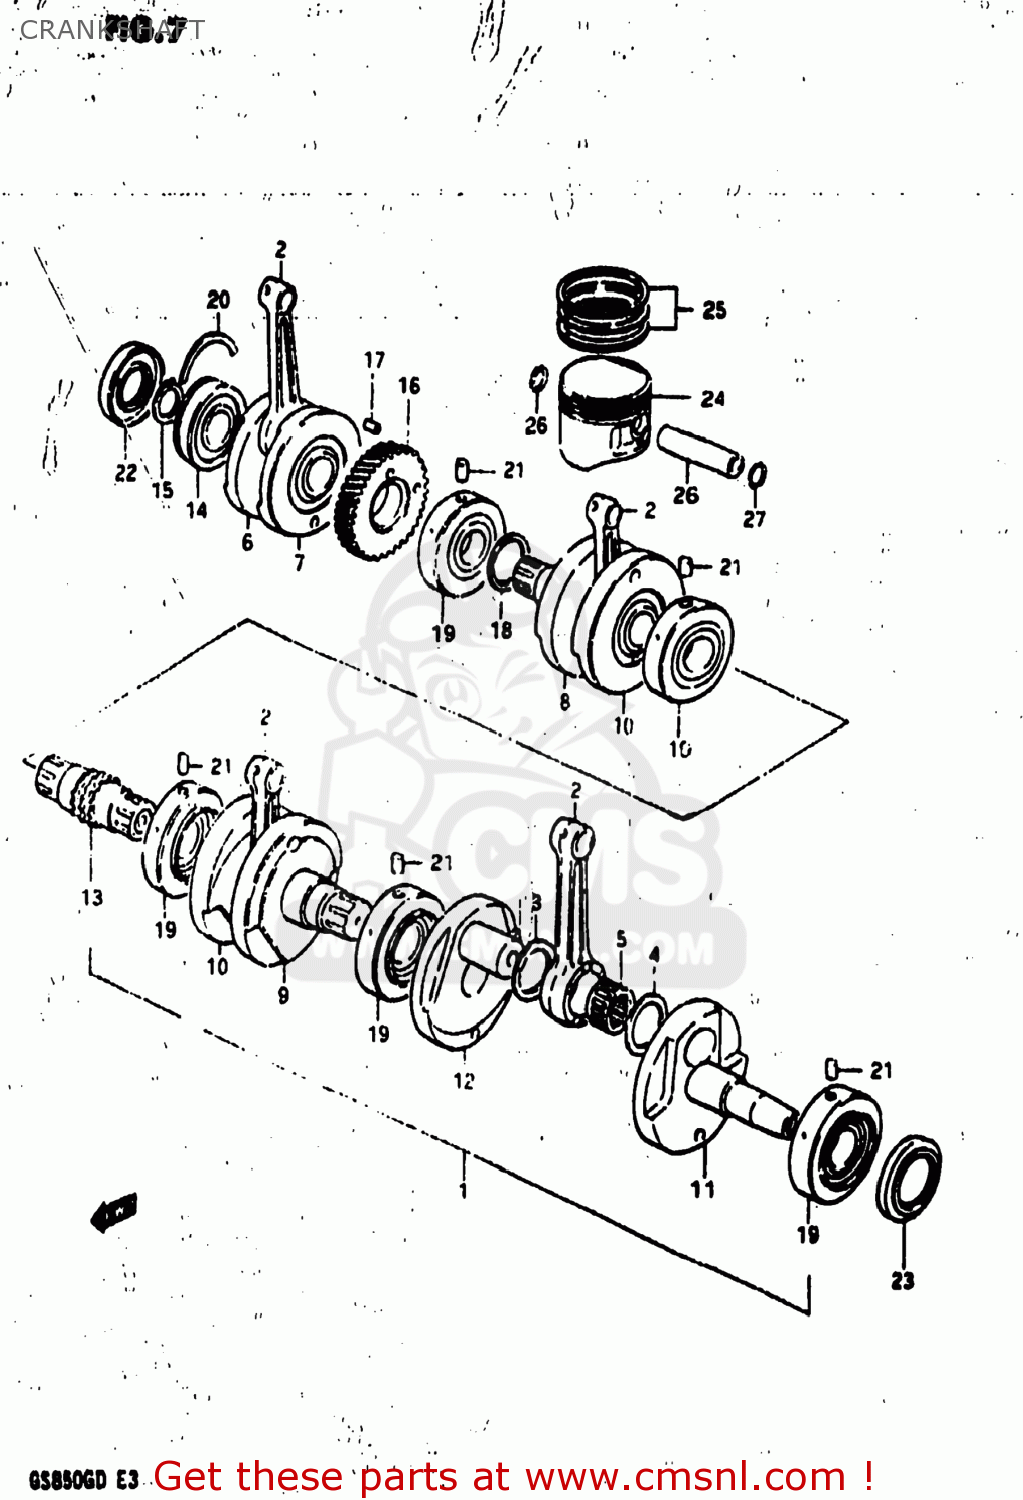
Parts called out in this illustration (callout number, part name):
1	CRANKSHAFT ASSEMBLY
2	ROD,CONNECTING
3	WASHER (29X48X2)
4	WASHER (29X48X1)
5	BEARING(29X39X20)
6	CRANKSHAFT
7	WEB,CRANK,RIGHT
8	CRANKSHAFT
9	CRANKSHAFT, MIDDLE LH
10	WEB,CRANK,MIDDLE
11	CRANKSHAFT,LEFT
12	WEB,CRANK,LEFT
13	SHAFT,TIMING CHAIN DRIVE
14	BEARING(30X72X19)
15	CIRCLIP,30MM
16	GEAR,PRIMARY DRIVE
17	PIN
18	WASHER
19	BEARING
20	C RING
21	PIN
22	SEAL,OIL(30X72X11)
23	OIL SEAL
24	PISTON
25	RING SET,PISTON
26	PIN,PISTON
27	CIRCLIP
